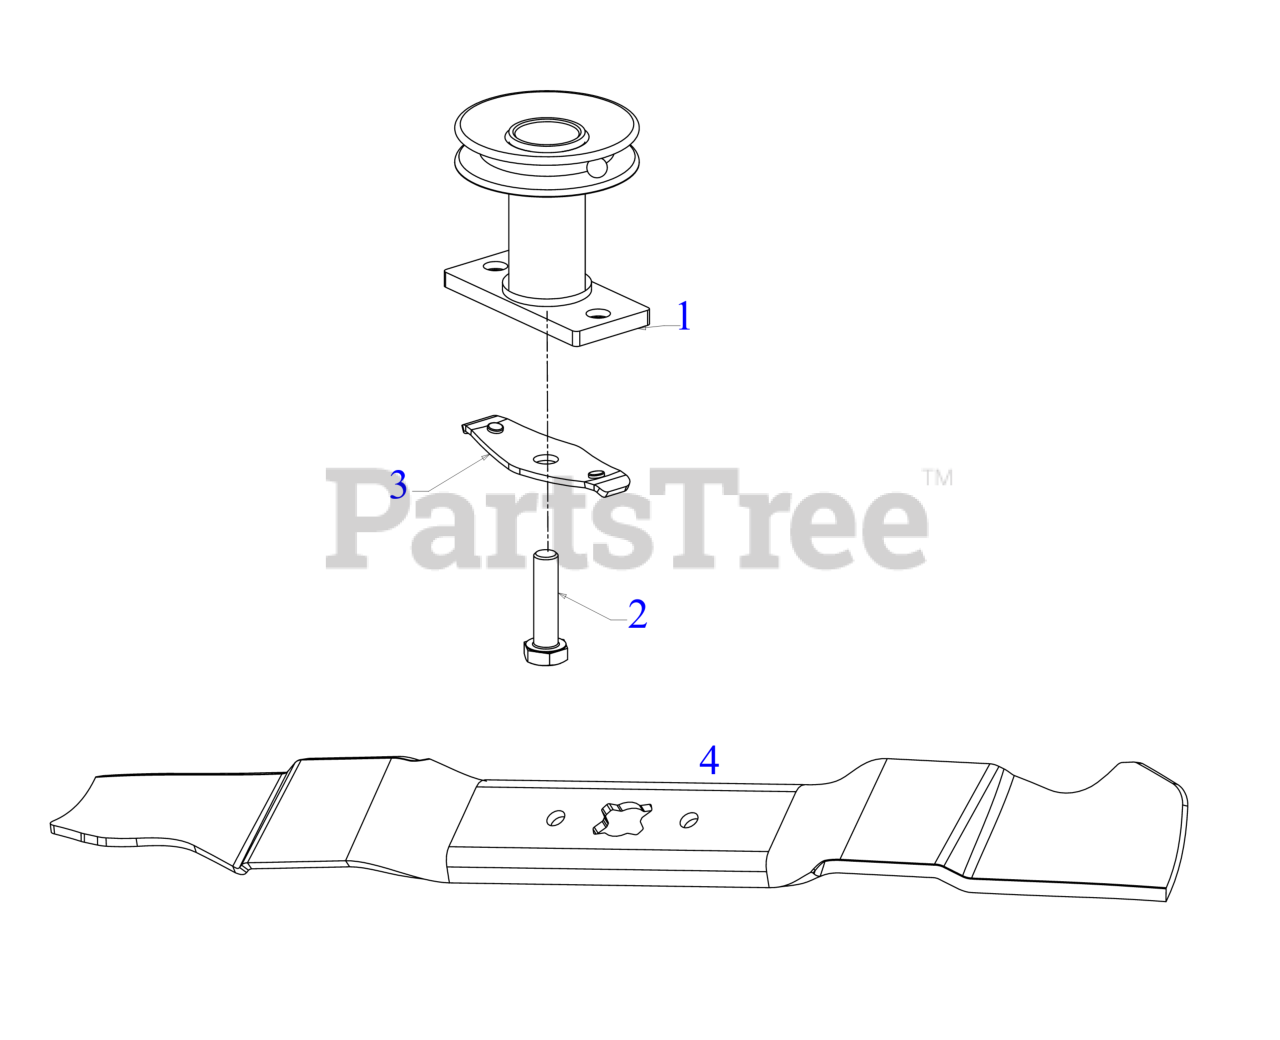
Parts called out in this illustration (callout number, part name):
1	ADAPTER ASSEMBLY-7/8"
2	SCREW 3/8-24 x 1.50 GR8
3	BLADE BELL SUPPORT
4	21" BLADE (MULCH)
4	Cub Cadet 21" MULCH BLADE
4	Genuine Factory Parts 21" MULCH BLADE
4	BLADE-21" MULCHING
4	21" BLADE (MULCH) (XTREME)
